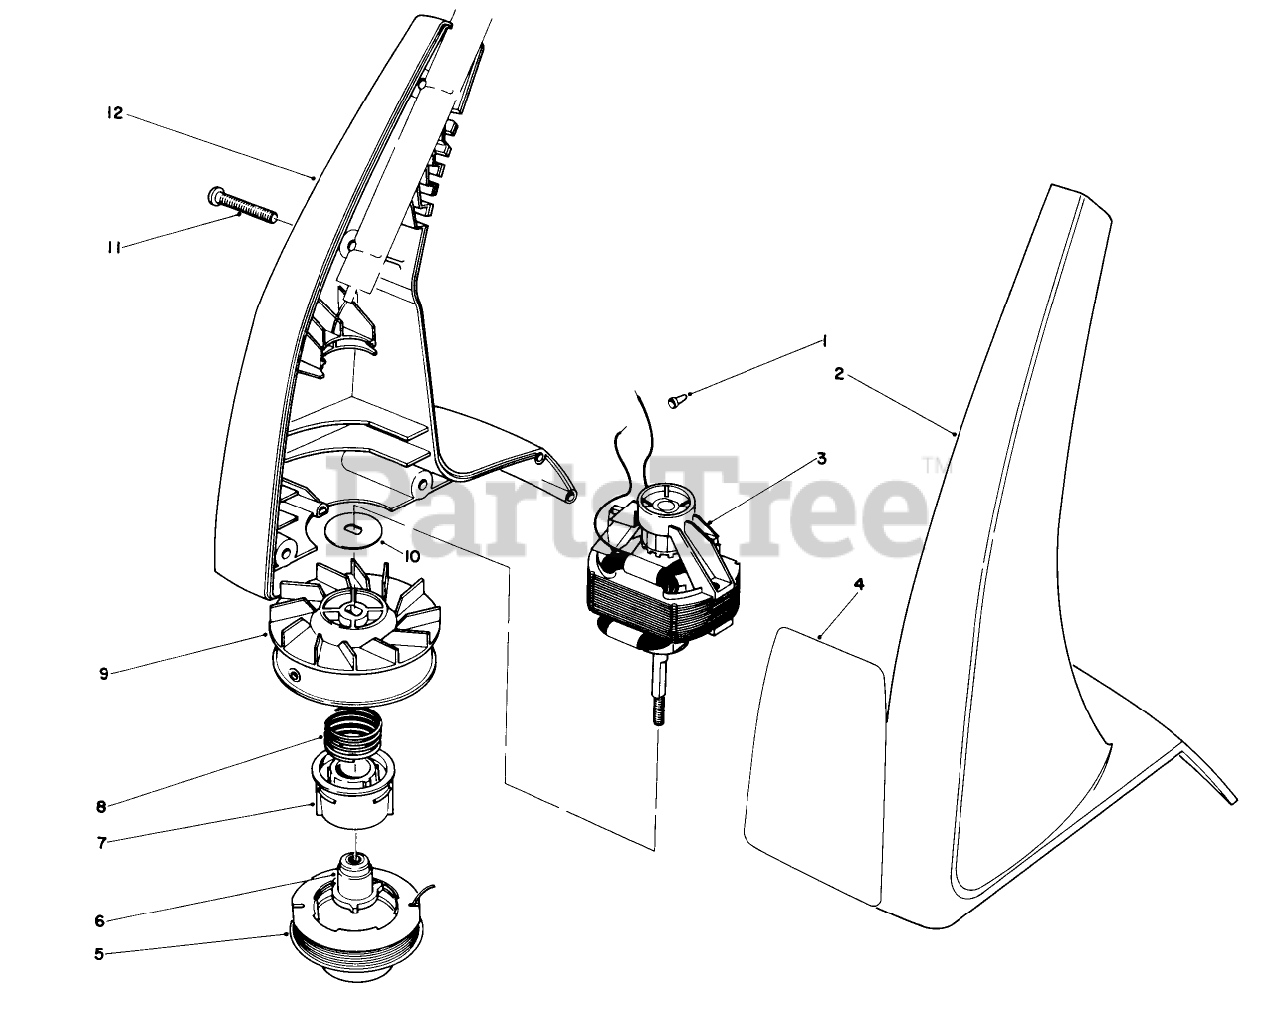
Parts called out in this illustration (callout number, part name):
3	Motor
5	Cutting Line (12- .05 Dia.)
6	DRIVER
7	CORE - SPOOL
9	Drum w/Eyelet
13	Rivet
14	Blade-Knife
